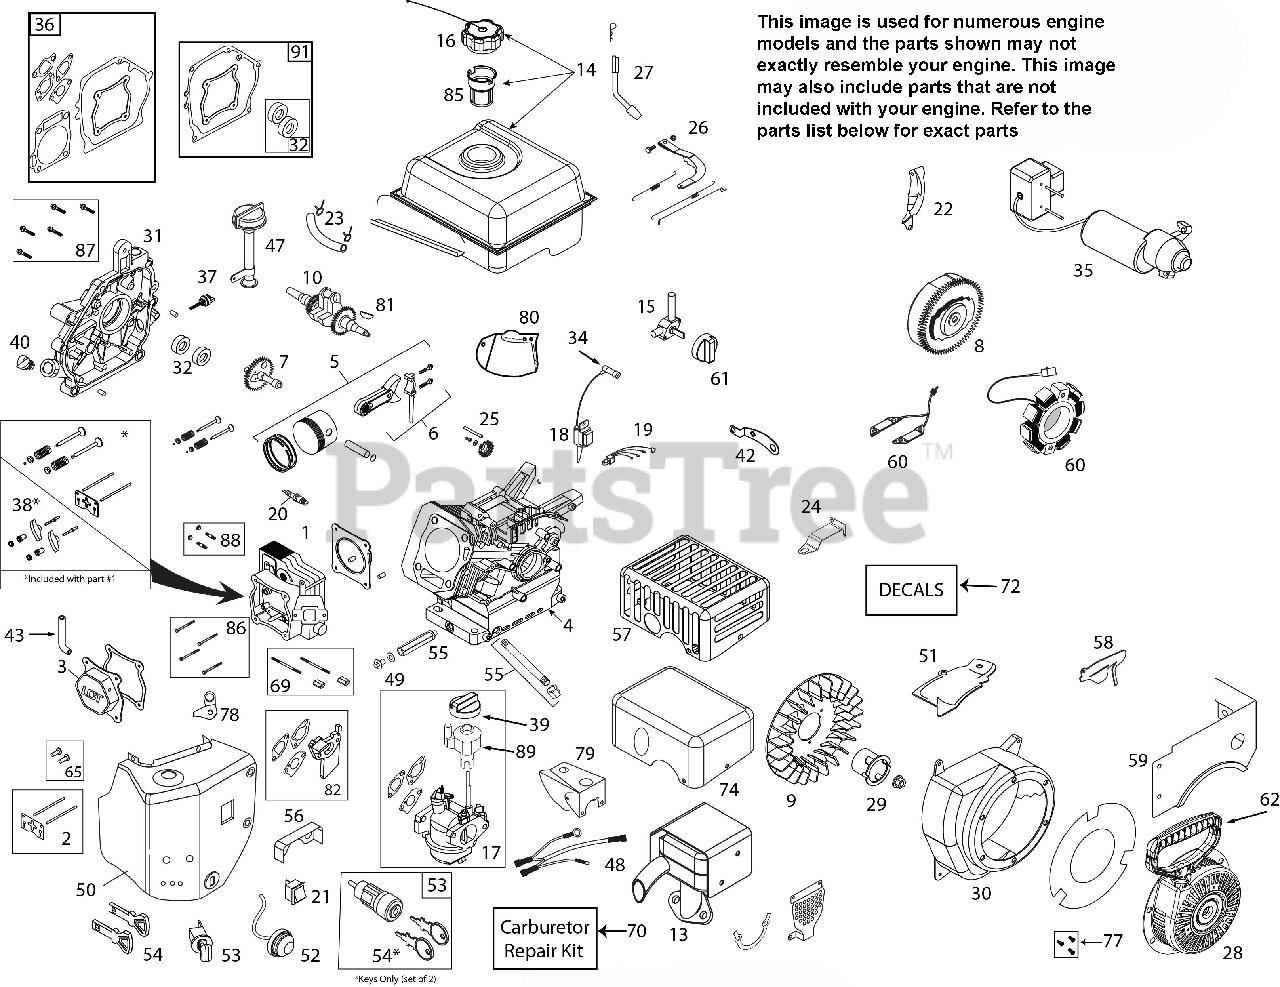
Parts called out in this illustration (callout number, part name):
1	CYLINDER HEAD ASSY (W/GASKET)
2	PUSH ROD & PLATE KIT (W/GASKT)
3	VALVE COVER (W/GASKET)
4	CYLINDER
5	PISTON & ROD ASSEMBLY
6	CONNECTING ROD ASSEMBLY
7	CAMSHAFT - MCR
8	FLYWHEEL - ELECTRIC START
9	COOLING FAN - FLYWHEEL
10	CRANKSHAFT (#18 KEYED)
13	MUFFLER ASSEMBLY
14	FUEL TANK ASSY
15	FUEL TANK ON/OFF VALVE
16	CAP, FUEL TANK BLACK
17	CARBURETOR (W/GASKETS)
18	IGNITION COIL (CDI) (STANDARD)
20	SPARK PLUG, ARIENS AX
21	ON/OFF SWITCH - ROCKER (RED)
22	SHIELD - FLYWHEEL (ELECTRIC)
23	FUEL HOSE KIT 1/4-230MMW/CLMPS
24	SPEED CONTROL BRACKET (FIXED)
25	GOVERNOR GEAR ASSEMBLY
26	GOVERNOR ARM & LNK KIT 3600RPM
27	GOVERNOR ARM PADDLE
28	RECOIL STARTER ASSY RND-BLACK
29	STARTER CUP RND STYLE STARTER
30	BLOWER HSG W/INTEGRATED BAFFLE
31	CRANKCASE COVER-HIGH, PRESS IN
32	OIL SEAL KIT(2 PCS 3/4" CRANK)
34	SPARK PLUG BOOT (W/MTL SHIELD)
35	120V ELECTRIC STARTER
36	ENGINE GASKET KIT
37	SMALL BLACK OIL DIPSTICK
38	ROCKER ARM KIT (W/GASKET)
39	CHOKE CONTROL KNOB (RED)
40	NON-REMOVABLE PLASTIC PLUG
43	BREATHER TUBE
47	HIGH OIL-FILL TUBE/DIPSTICK
48	WIRE HARNESS
49	OIL DRAIN PLUG (W/WASHER)
50	HEATER BOX KIT
52	PRIMER BULB WITH HOSE-SNOW (RED)
53	SAFETY KEY SWITCH (W/KEYS) (RED)
54	KEY, PUSH/PULL LCT (2/PACKAGE)
55	OIL DRAIN TUBE
57	CE COMPLIANT MUFFLER SHIELD
58	SHIELD - GOVERNOR LINKAGE
59	FUEL TANK SKIRT
61	FUEL CONTROL KNOB (RED)
65	TAPPET KIT (SET OF 2)
69	CARBURETOR STUDS & COUPLNG KIT
70	CARBURETOR REPAIR KIT
72	Ariens 208-254, 2016 Snow Label Kit
74	MUFFLER HEAT SHIELD COVER
77	RECOIL BOLT KIT
78	BREATHER TUBE BRACKET
79	CARBURETOR COVER
81	WOODRUFF FLYWHEEL KEY 5-PACK
82	CARBURETOR SPACER
85	FUEL TANK STRAINER
86	HEAD BLT KIT 136-179-208-254CC
87	CC COVER BLT KIT 179-208-254CC
88	MUFFLER MTG STUD KIT
91	CRANKCASE GASKET KIT 208GEN1&2
9999	HIGH ALT JET-208CC L10-1 CARB
9999	HARDWARE KIT (4 M6X10 FLG BLT)
